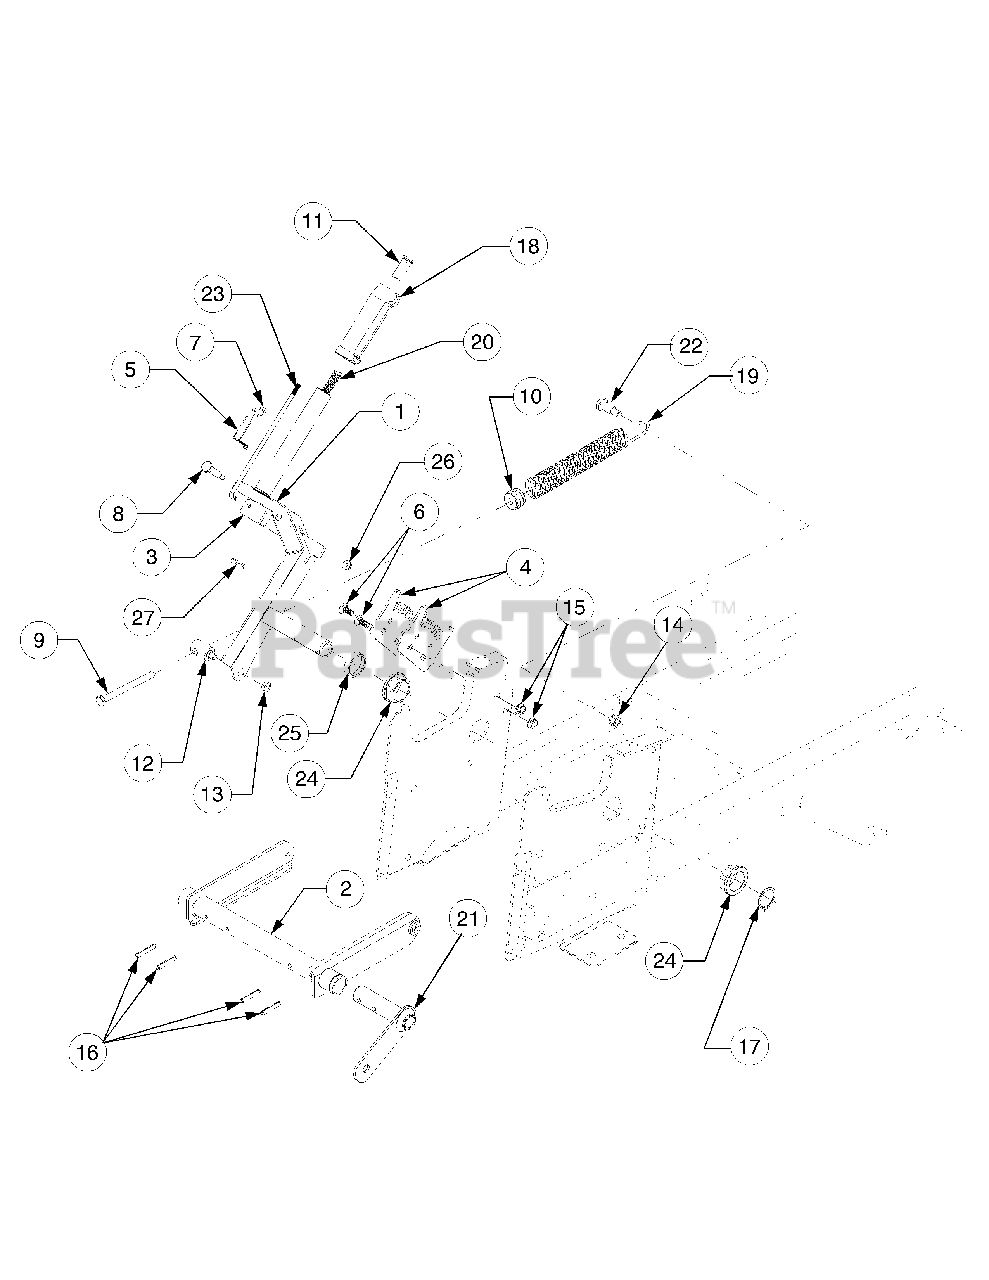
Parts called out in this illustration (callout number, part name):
2	Shaft Assembly, Lift
5	Indicator, Lift Height
6	Bolt, Carriage, 5/16-18 x .75
7	Screw, Hex Wash Tapp, 1/4 x .5
8	Screw, Shoulder, .374 x 1.375
9	Screw, Hex Cap, 3/8-16 x 4.25 GR5
10	Insert, Spring
11	Button, Handle
12	Ferrule, Adjustment
13	Nut, Hex Center Lock, Jam, 3/8-24
14	Nut, Hex Flanged Lock, 3/8-16
15	Nut, Hex Flanged Top Lock, 5/16-18
16	Pin, Spiral Spring, 1/4 Dia x 1.5
17	Ring, Snap, 1.25 Dia Shaft
18	Grip, Lift Handle
19	Spring, Extension
20	Spring, Compression
22	Bolt, Shoulder
23	Rod, Index
24	Bearing, Hex Flange, 1.25 ID
25	Spacer, 1.28 ID x 1.5 OD x .335 Lg
26	Nut, Hex Flange Lock, 1/4-20
27	Pin, Internal Cotter
